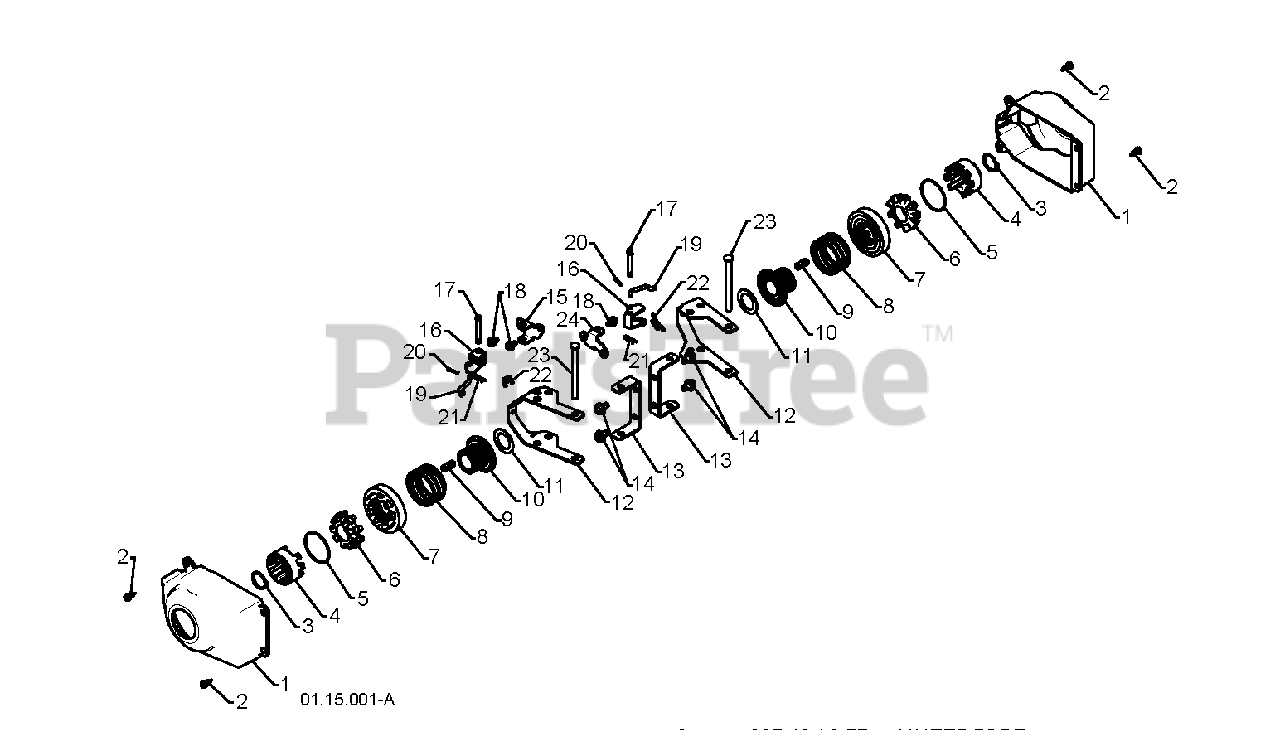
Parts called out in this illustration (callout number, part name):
1	COVER, POWER STEERING
2	SCREW, HEX HEAD, TAPPING
4	DRIVER WHEEL
5	RING, WIRE RETAINER
6	LOBE WHEEL
7	SLIDE.CLUTCH
8	SPRING, CLUTCH SLIDE
9	KEY, SQUARE 1/4 X .875
10	LOBE.AXLE
11	WASHER TRUST 1"
12	YOKE, STEERING
13	BRACKET.STEER.PNT.BLACK
15	BRKT.STEER.PIVOT.RH
16	BELLCRANK.STEER
17	PIN, STEERING BELLCRANK
19	LINK.STEER.YOKE
20	RETAINER CLIP
21	RETAINER CLIP PM
22	SPRING LATCH
23	PIN, STEERING LEVER
24	CONTROL SHAFT
